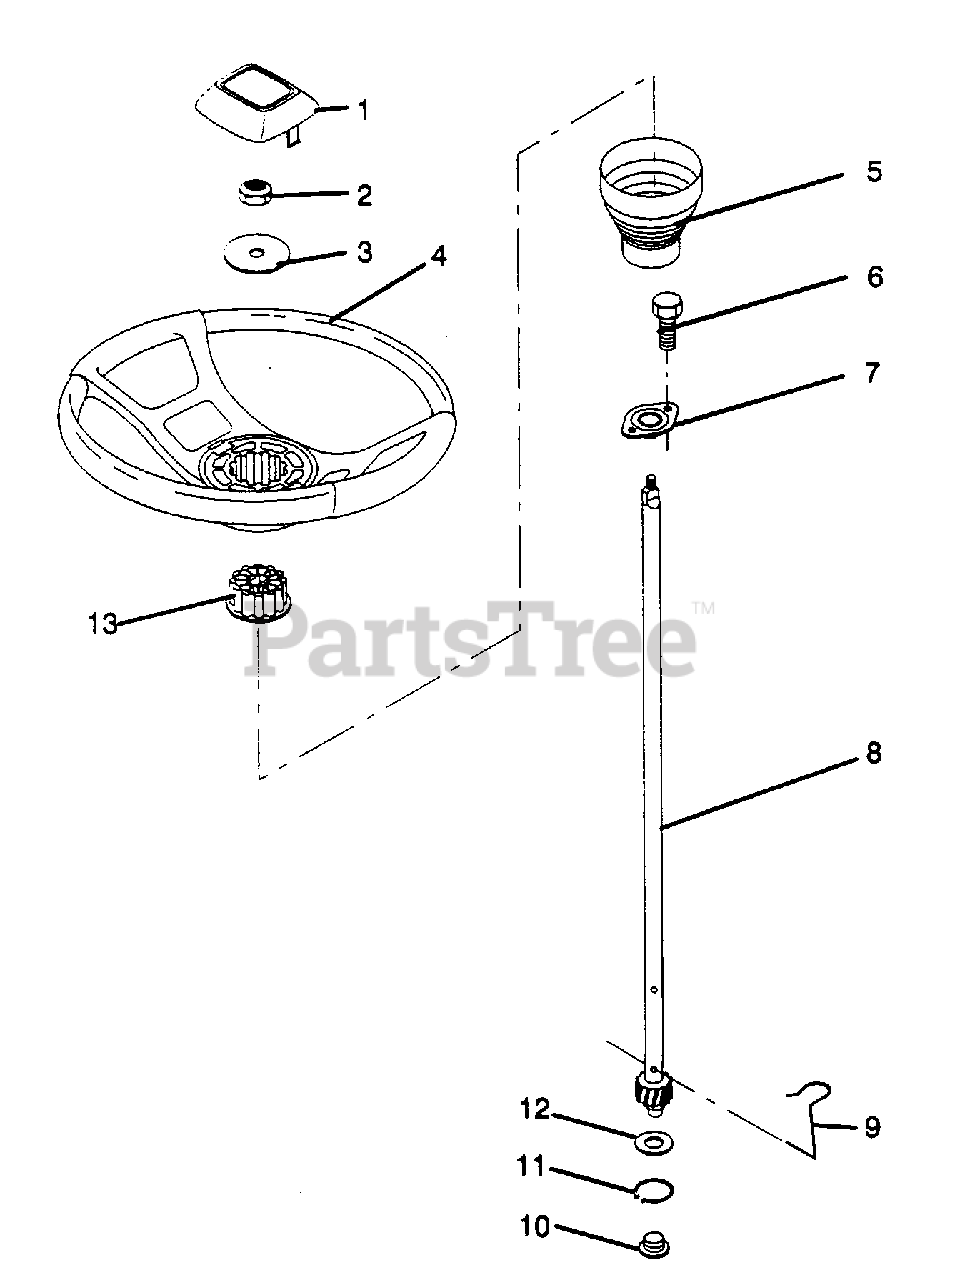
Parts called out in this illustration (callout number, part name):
1	Insert, Wheel, Steering (AYP part number)
2	Nut, Lock 3/8-24 UNF (AYP part number)
3	Washer 13/32 x 2 3/8 x 8 Ga. (AYP part number)
4	Wheel, Steering (AYP part number)
5	Sleeve, Steering (AYP part number)
6	Screw, Hex SLFTP #10-16 x 1/2 TY-B (AYP part number)
7	Bushing, Steering (AYP part number)
8	Shaft, Steering (AYP part number)
9	Clip, Steering (AYP part number)
10	Bushing, Lower, Steering (AYP part number)
11	Ring, Retaining (AYP part number)
12	Washer 21/32 x 1 x 16 Ga. (AYP part number)
13	Adaptor, Wheel, Steering (AYP part number)
